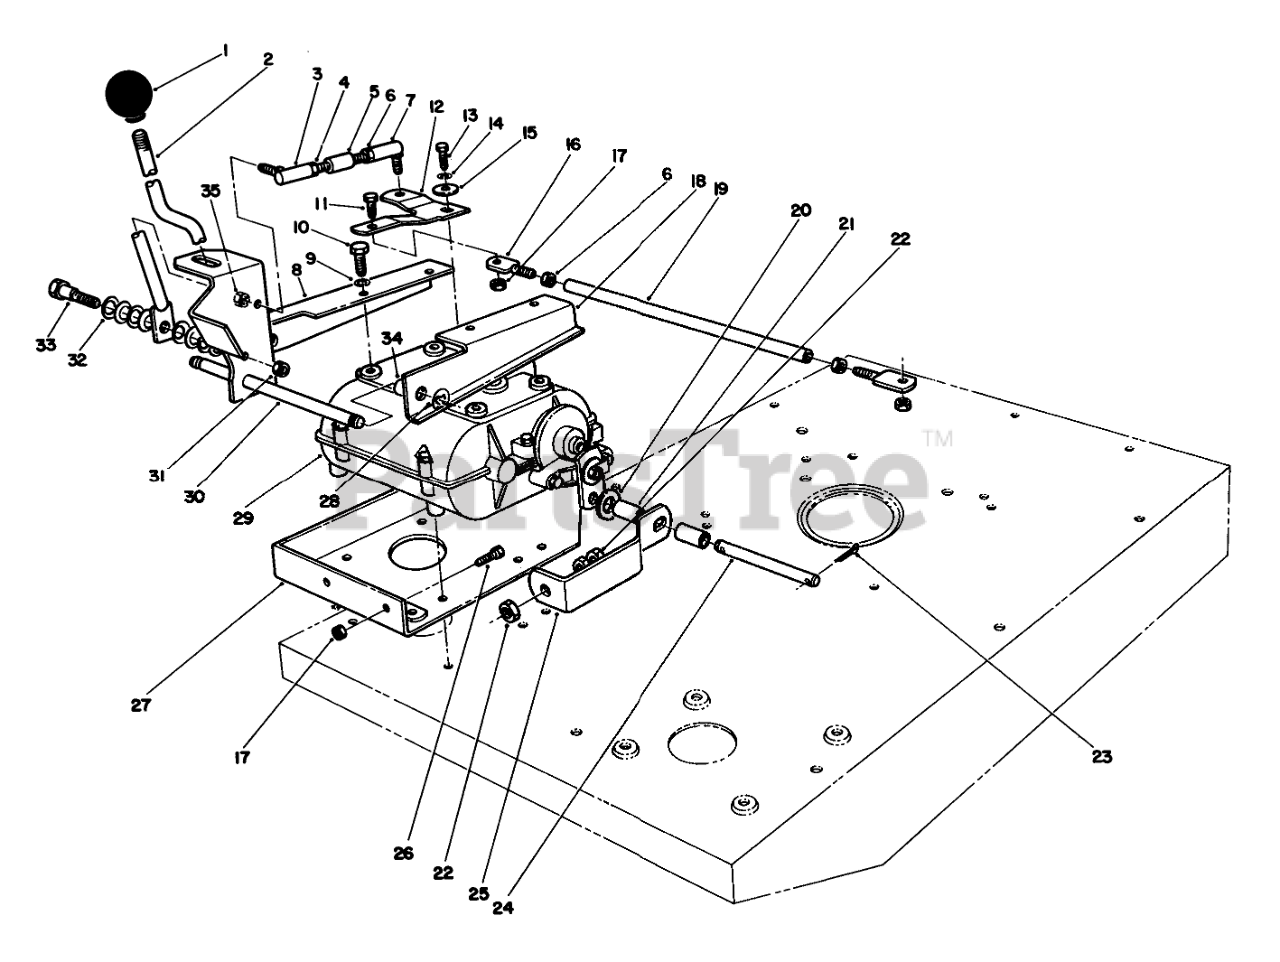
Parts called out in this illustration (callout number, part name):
2	SHIFT LEVER B
3	JOINT-BALL, LH
4	NUT-JAM
5	Tie Rod Shift (Incl. Ref. #3, 4, 6 & 7)
6	NUT-JAM
7	JOINT-BALL
8	Bracket-Shift R.H.
9	WASHER-LOCK
10	SCREW-HWHTF
11	SCREW-HH
12	RH SHIFT ARM
13	SCREW-HH
14	WASHER-LOCK
15	SPACER
16	ROD END BRG
17	NUT-LOCK, NI
18	LH SHIFT BRACKET
19	SHIFT LINK SHAFT
20	WASHER-FLAT
21	SPACER
22	NUT-JAM
23	PIN-COTTER
24	PIN-BRAKE, LINKAGE
25	BRAKE ADJUSTER
26	SCREW-HH
27	TRANSMISSION PAN WA
28	RING-RETAINING, EXTERNAL
29	TRANSMISSION RH
30	SHIFT PIVOT WA B
31	NUT-LOCK, NI
32	WASHER-BELLEVILLE
33	BOLT-SHOULDER
34	BUSHING
35	NUT-LOCK
